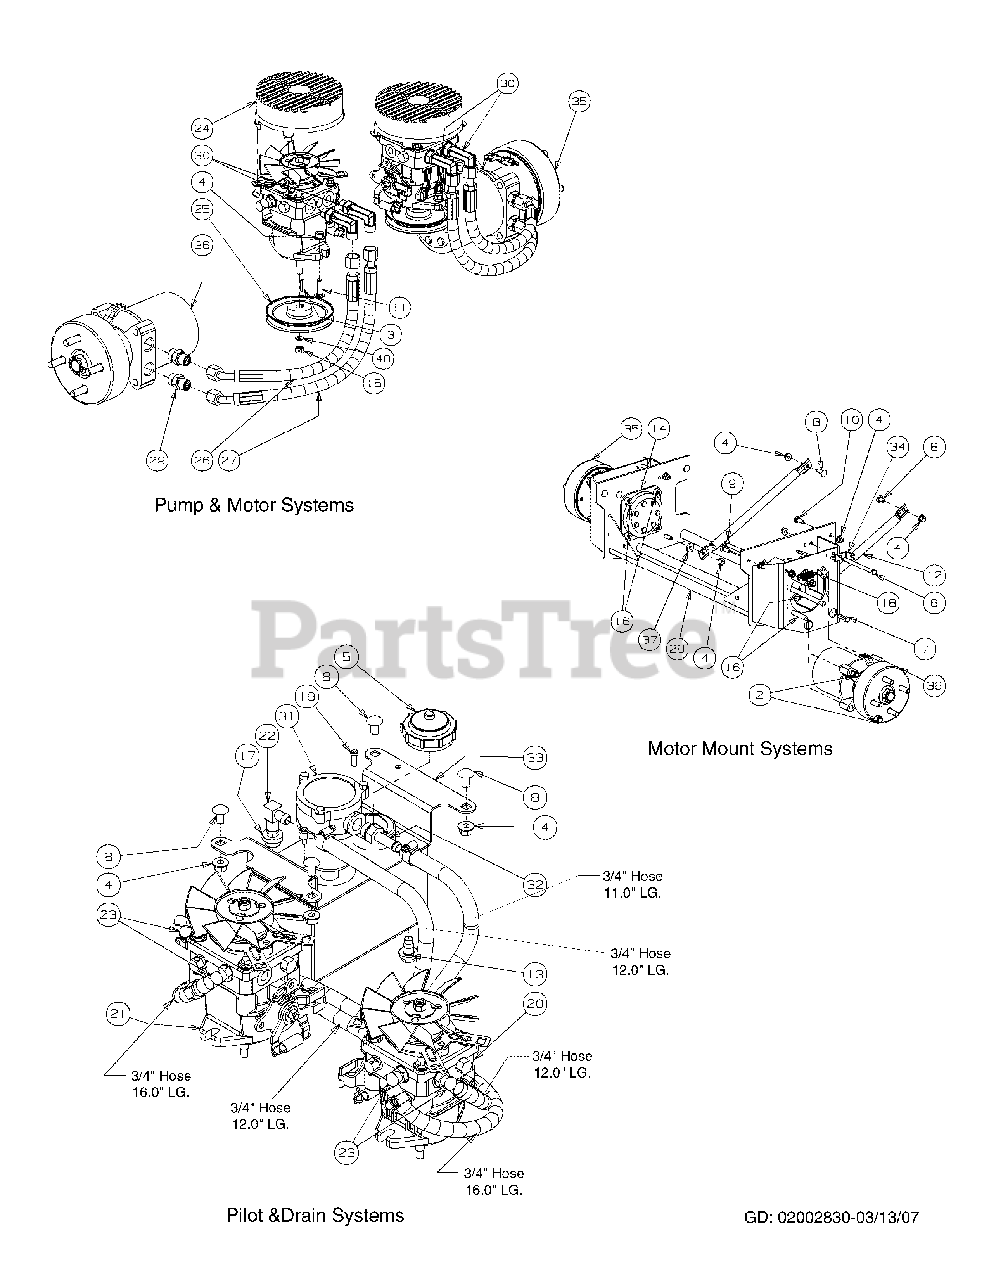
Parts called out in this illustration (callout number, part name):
1	Hose Clamp, 1/2
2	Washer lock 3/8 zinc
3	Key, 3/16" x 7/8"
4	Flange Lock Hex Nut, 3/8-16
5	Cap, Hydro Oil Tank
6	Hex Cap Screw 3/8-16 x 5.00
7	Hex Cap Screw, 3/8 -16 x 1.25
8	Carriage Bolt, 3/8-16 x .75 LG.
9	Carriage Bolt, 3/8-16 x 5.50
10	Carriage Bolt, 3/8-16 x 1
11	Carriage Screw, 3/8-16 x 1.25
12	Strut Frame
13	Oil Pan Drain Plug w/ Seal
14	Hydro Wheel Motor Backup Plate
15	Hex Nut, 3/8-24
16	Socket Head Capscrew, 1/2-13; 6-1/2
17	Grommet Fitting, .54 ID x .78 OD
18	Spring Extension, .740 OD x 2.656
19	Socket Low Head Cap Screw, 1/4-20 x 0.75
20	Hydro Pump, BDP-12, RH
21	Hydro Pump, BDP-12, LH
22	Fitting Elbow Spur, 5/8 x 1/2
23	Fitting Elbow, 9/16 x 1/2
24	Fan Pump Shroud
25	Hydro Pump Pulley
26	Short Pressure Hose Assembly
27	Long Pressure Hose Assembly
28	Hydro Motor Frame Assembly
29	Adaptor Fitting, 8 x 10
30	Adaptor, 8 x 8
31	Hydraulic In-Tank Filter includes:
32	Fitting, 3/4 ORB x 1/2 Tube
33	Hydraulic Tank Assembly
34	Rear Cable Mounting Bracket
35	Hydro Motor, Left Hand Assembly w/ Brake & Drum
36	Hydro Motor, Right Hand Assembly w/ Brake & Drum
37	Idler Washer
38	Fuel Hose, .50 ID x .75 OD (79 inches)
39	Tee Fitting, 1/2
40	Flat Washer, 3/8
